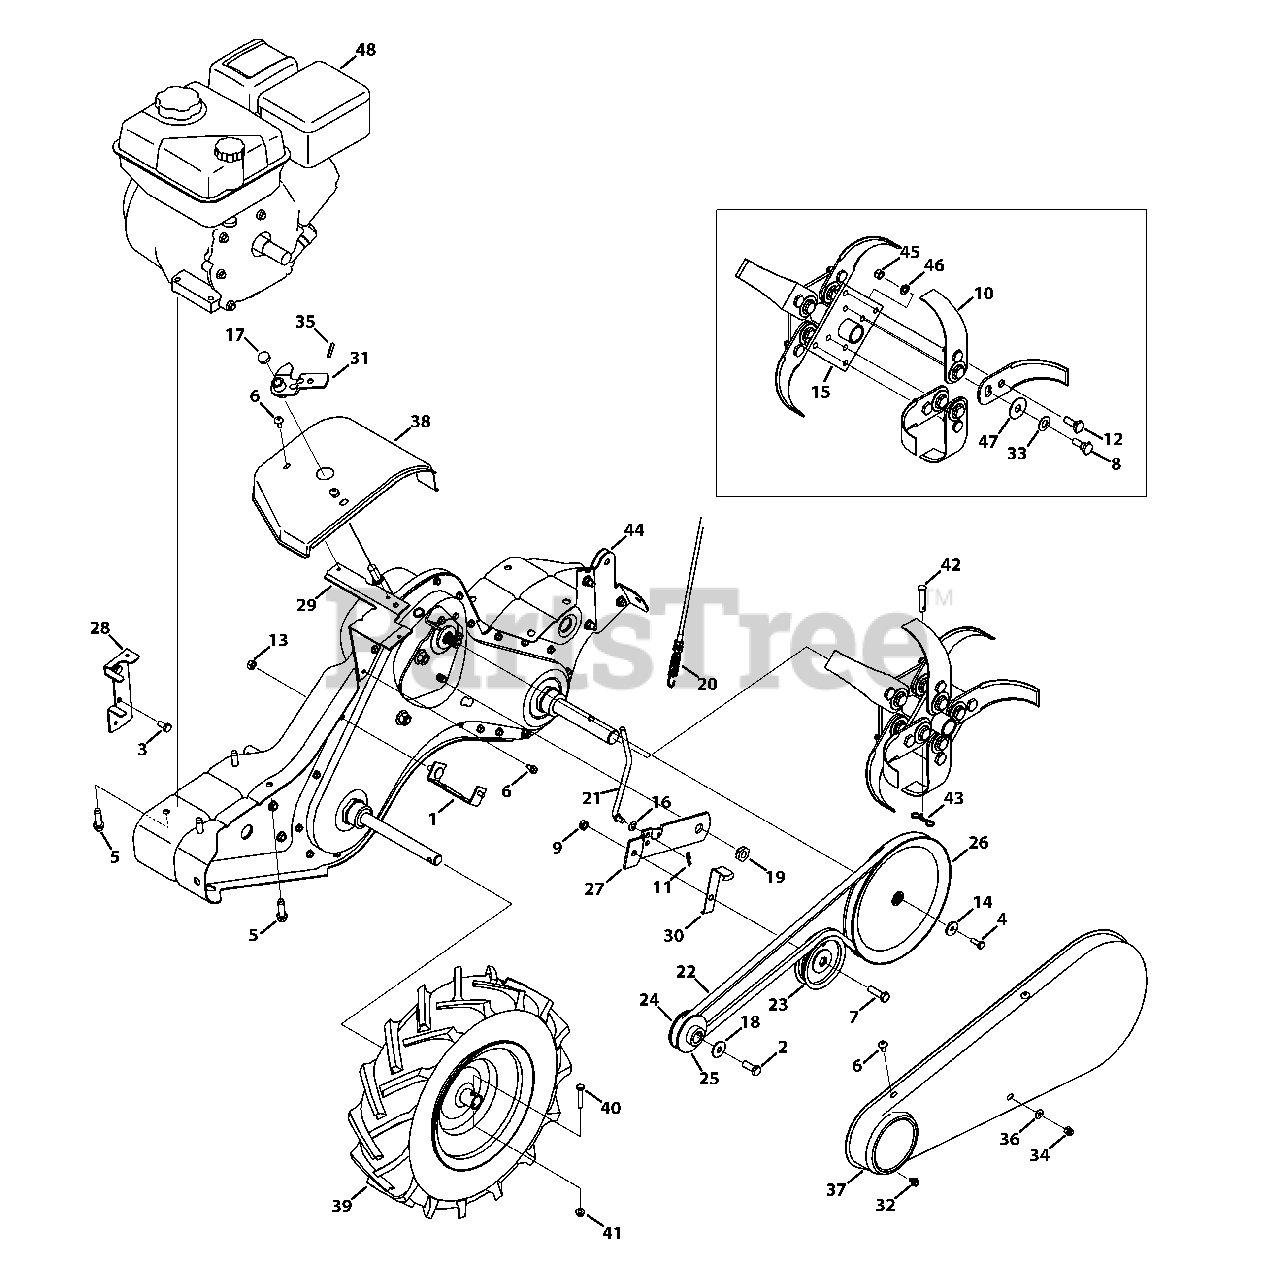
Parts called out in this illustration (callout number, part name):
1	Belt Cover Bracket Assembly
2	Hex Screw, 3/8-24 x 1.00
3	Hex Lock Screw, 5/16-24 x .625
4	Hex Lock Screw, 1/4-28 x .625
5	Screw, 3/8-16 x 1.250
6	Hex Washer Screw, 1/4-20 x 0.625
7	Hex Screw, 3/8-16 x 1.25
8	Shoulder Screw, 3/8-24 x 1/2 x .325
9	Jam Lock Nut, 3/8-16
10	Articulating Tine
11	Cotter Pin, .072 x 1.13
12	Shoulder Screw, 3/8-24 x 1/2 x .180
13	Flange Lock Nut, 5/16-18
14	Flat Washer, .265 x .938 x .120
15	Tine Adaptor Assembly
16	Washer, Spring, .317 x .625 x .020
18	Bell Washer, .396 x 1.140 x .095
19	Shoulder Nut, 7/16-20
20	Clutch Cable
21	Idler Pulley Rod
23	Flat Idler Pulley, 3.75
24	Engine Pulley, Inner Half
25	Engine Pulley, Outer Half
26	Input Pulley, 4 x 8.594
27	Idler Pulley Bracket
28	Belt Keeper Bracket
29	Shift Cover Bracket
30	Idler Belt Keeper
31	Shift Crank Assembly
32	Screw, 1/4-20:0.375
33	Bell Washer, .525 x 1.00 x .050
34	Lock Nut, 1/4-28
35	Spiral Pin, 3/16 x 1.00
36	Flat Washer, .271 x .630 x .065
37	Belt Cover
38	Shift Cover
39	Wheel, 16 x 4.6 x 8
40	Hex Screw, 1/4-20 x 1.50
41	Flange Lock Nut, 1/4-20
42	Clevis Pin, .375 x 1.75
43	Cotter Pin
44	Complete Gear Case Assembly
45	Hex Lock Nut, 3/8-24
46	Lock Washer, 3/8
47	Flat Washer, .51 x 1.5 x 0.07
48	Replacement Engine
